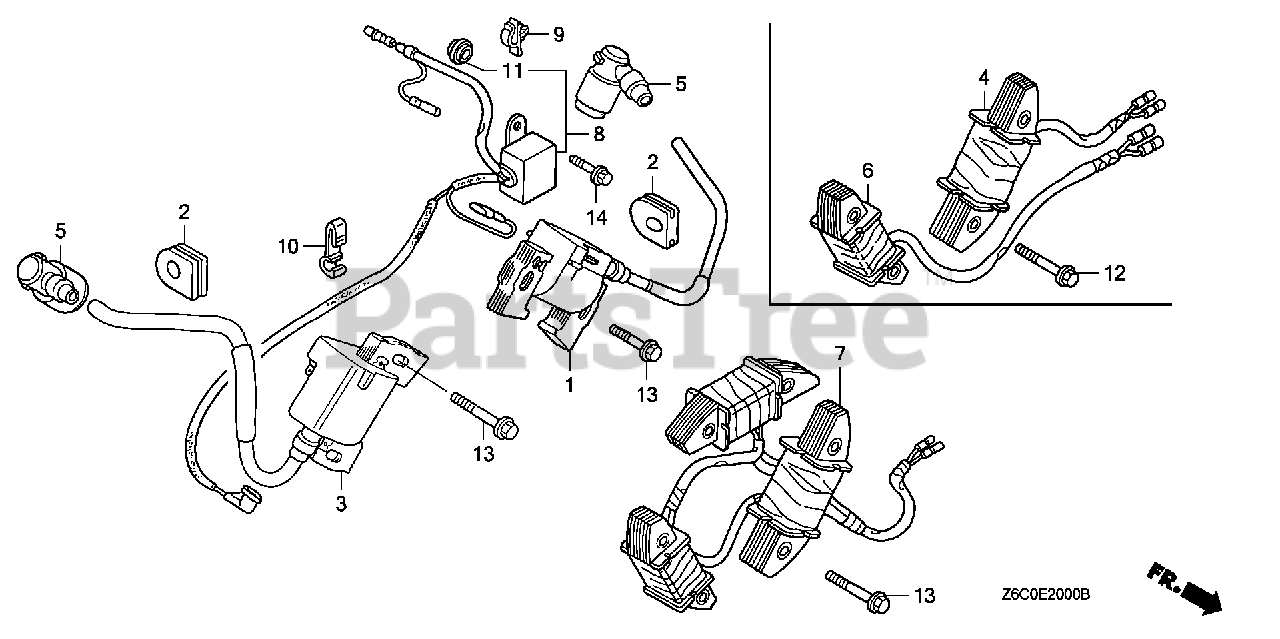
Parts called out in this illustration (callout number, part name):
1	COIL ASSY., IGNITION (200MM) (BLACK) (L. SIDE)
2	GROMMET, IGNITION WIRE
3	COIL ASSY., IGNITION (215MM) (GRAY) (L. SIDE)
5	CAP ASSY., NOISE SUPPRESSOR
7	COIL ASSY., CHARGE (12V/20A)
8	DIODE ASSY., ENGINE STOP
10	CLAMP, WIRE
11	GROMMET, TOOL
13	BOLT, FLANGE (6X32)
14	BOLT, FLANGE (6X8)
